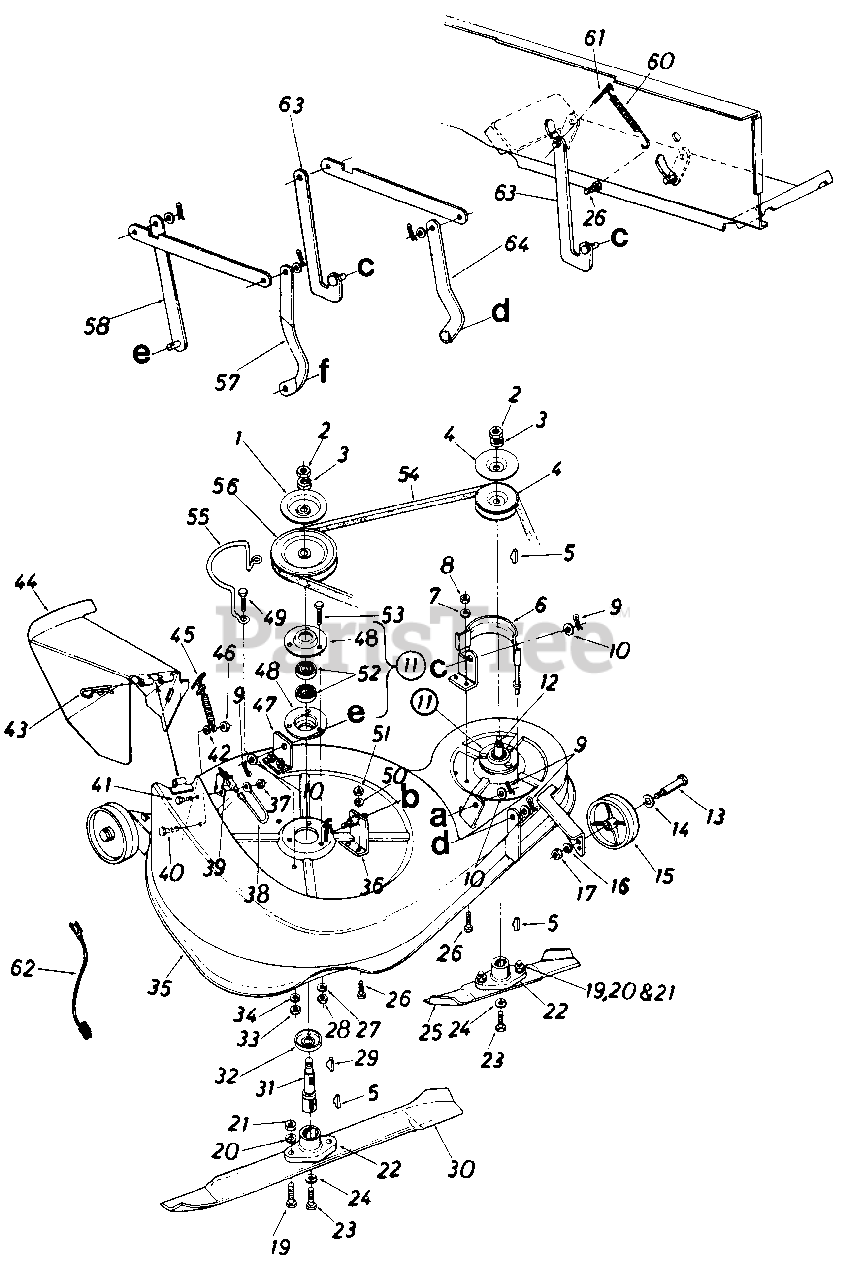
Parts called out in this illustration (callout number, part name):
1	Brake Disc
2	Hex Jam Nut 5/16-18 Thd.
3	Bell-Wash. .630" I.D. x 1.25" O.D.
4	Pulley Ass'y. 3.5" O.D. x 5/8
5	# Hi-Pro Key 5/32" x 5/8" Dia.
6	Belt Guard Ass'y.-L.H.
7	L-Wash. 5/16" I.D.
8	Hex Nut 5/16-18 Thd.
9	Internal Cotter Pin 1/2" Dia.
10	Fl-Wash. .531" I.D. x .93" O.D.
11	Blade Spindle Ass'y.
12	Blade Spindle
13	Shld. Bolt .498" Dia. x 1.635
14	Bell-Wash. .400" I.D. x .88" O.D.
15	Deck Wheel 5.0" x 1.38"
16	L-Wash. 5/16" I.D.
17	Hex Nut 3/8-16 Thd.
19	Hex Bolt 5/16-24 x 1.00" Lg. (Grade 5)
20	L-Wash. 5/16" I.D.
21	Hex Nut 5/16-24 Thd.*
22	Blade Adapter
23	Hex Bolt 3/8-24 x 1.50" Lg. (Grade 5)
24	L-Wash. 3/8" I.D. H.D.
25	13" Blade
26	Hex Bolt 5/16-18 x .75" Lg.
27	L-Wash. 5/16".1.D.
28	Hex Nut 5/16-18 Thd.
29	#6 Hi-Pro Key 5/32" x 5/8" Dia.
30	24" Blade
31	Blade Spindle
32	Bearing Shield
33	Hex Nut 5/16-18 Thd.
34	L-Wash. 5/16" I.D.
35	36" Deck Ass'y.
36	Deck Hanger Brkt.-R.H. Front
37	Hex Nut 1/4-20 Thd.
38	Ground Wire
39	Safety Switch
40	Truss Mach. Scr. 1/4-20 x .50" Lg.
41	Hex Bolt 1/4-20 x .50" Lg.
42	Fl-Wash. .281" I.D. x .50" O.D.
43	Internal Cotter Pin
44	Chute Deflector Ass'y.
45	Spring Latch Ass'y.
46	Hex Nut 1/4-20 Thd.
47	Deck Hanger Brkt.-R.H. Rear
48	Brg. Housing 1.85" I.D.
49	Hex Bolt 5/16-18 x .75" Lg.
50	L-Wash. 5/16 I.D.
51	Hex Nut 5/16-18 Thd.
52	Ball Brg. .787" I.D. x 1.85" O.D.
53	Hex Bolt 5/16-18 x .75" Lg.
54	"V"-Belt 1/2" x 71 " Lg. (Full A Sec.)
55	Belt Guard
56	Pulley 6.0" O.D. x 5/8"
57	Link Deck Hanger-Front-R.H
58	Link Deck Hanger Ass'y.-Rear R.H.
60	Ext. Spring
61	Cotter Pin 1/8" Dia. x 1.25" Lg.
62	Wire Lead
63	Link Deck Hanger Ass'y.-Rear L.H.
64	Link Deck Hanger Ass'y.-Front L.H.
